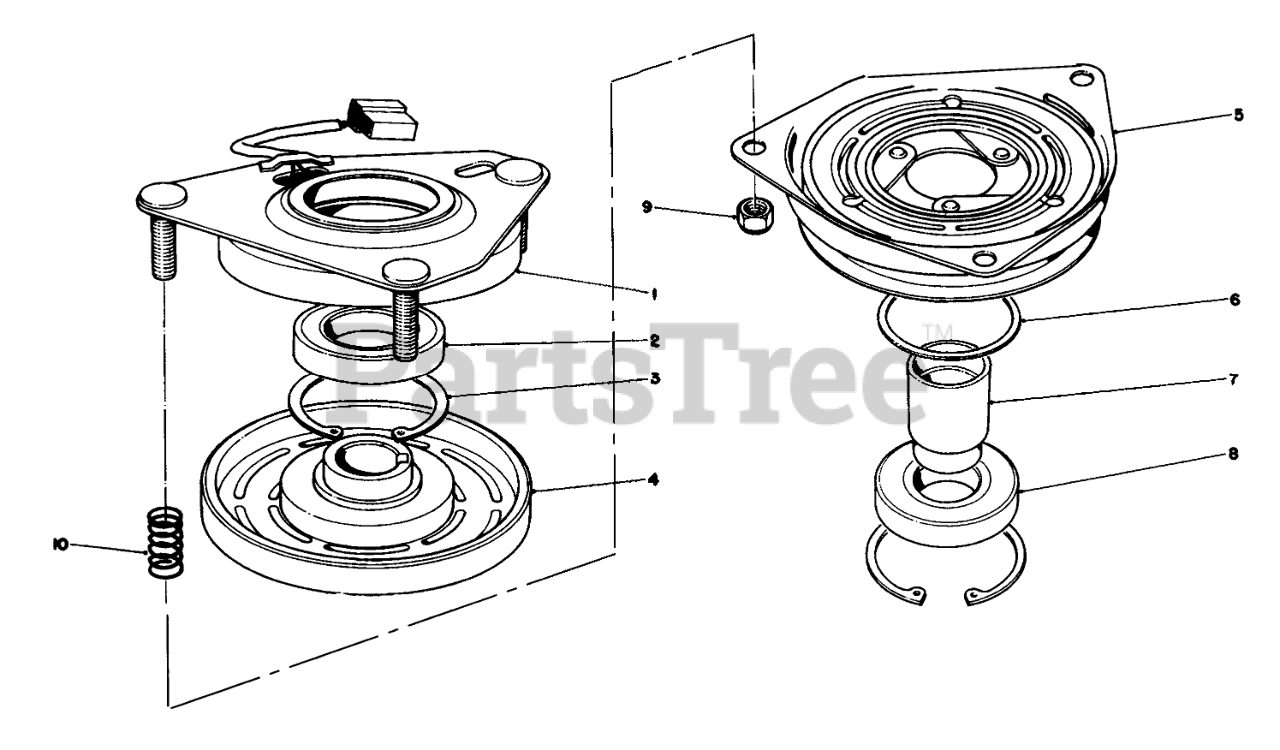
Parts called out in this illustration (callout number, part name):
1	Field Assembly (Incl. Ref. #2 & 3)
2	BEARING-FIELD
3	RING-RETAINING
4	Field Coil, Rotor & Bearing (Incl. Ref. #1)
5	Armature & Pulley Assembly (Incl. Ref. #3, 6, 7 & 8)
6	SPACER-BEARING, PULLEY
7	COLLAR-BEARING
8	BEARING-PULLEY
9	NUT-LOCK
10	SPRING
